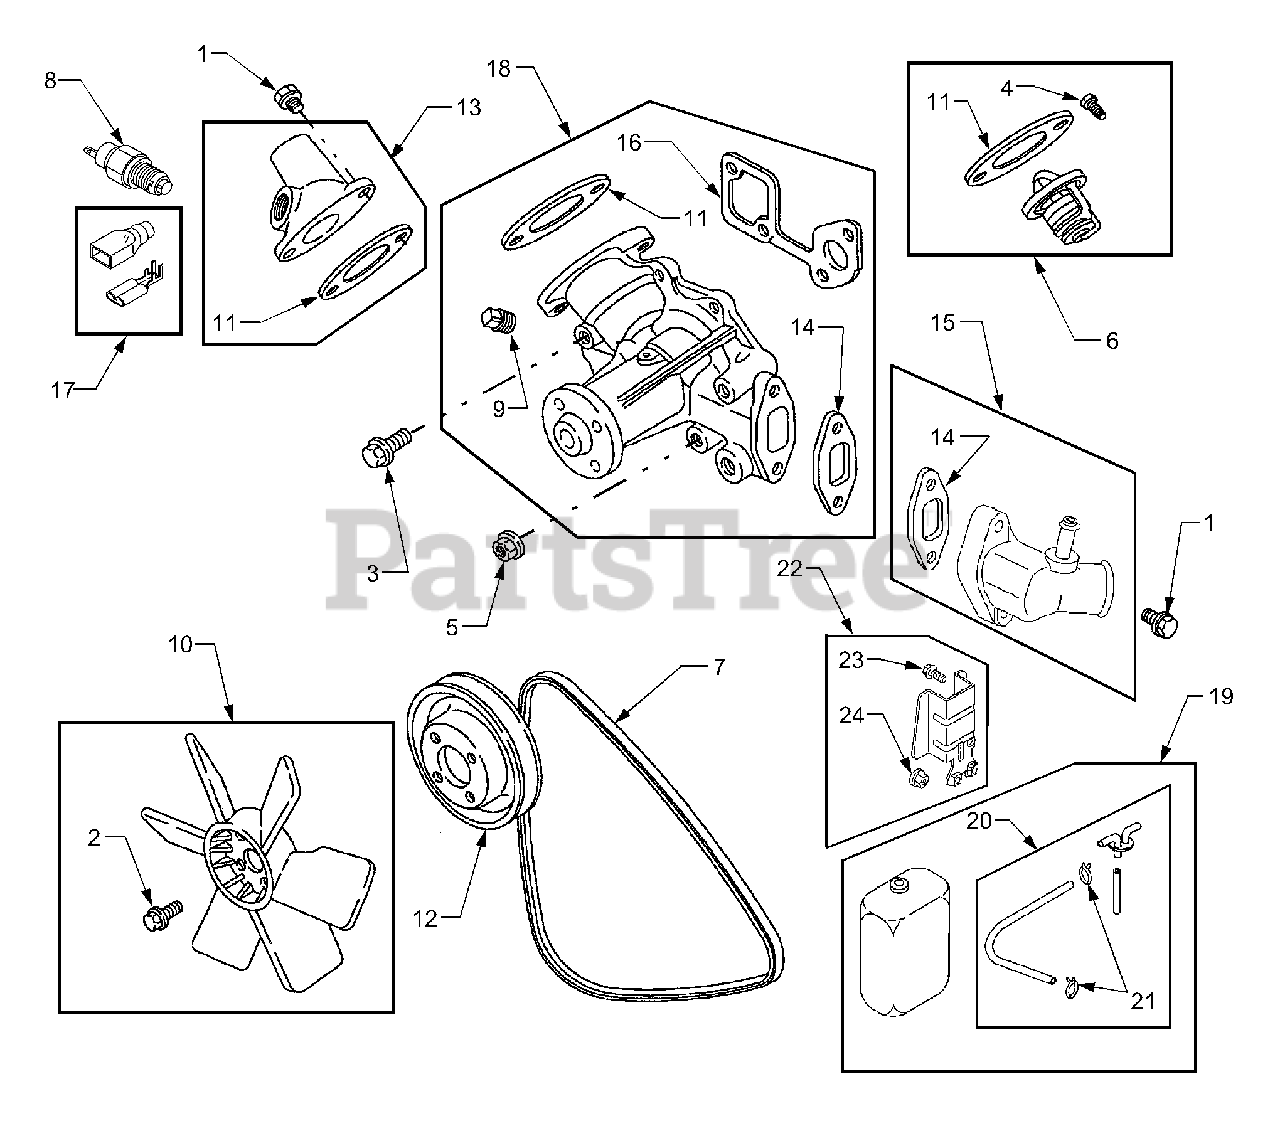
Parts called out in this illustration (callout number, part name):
1	Screw, Hex, 6mm
2	Screw, Hex,
3	Screw, Hex, 8mm
4	Screw, Metric
5	Nut, Hex Metric
6	Thermostat
7	Belt, V
8	Switch, Coolant Temperature
10	Fan, Radiator
11	Gasket, Outlet
12	Pulley, Pump
13	Housing, Outlet
14	Gasket, Inlet Housing
15	Housing, Inlet
16	Gasket, Water Pump
17	Connector, Coolant Temp. Switch
18	Pump, Water
19	Tank, Reserve
20	Cap, Reserve Tank
21	Clamp, Hose
22	Bracket, Reserve Tank Mtg.
23	Screw, Mtg. Bracket
24	Nut, Mtg. Bracket
